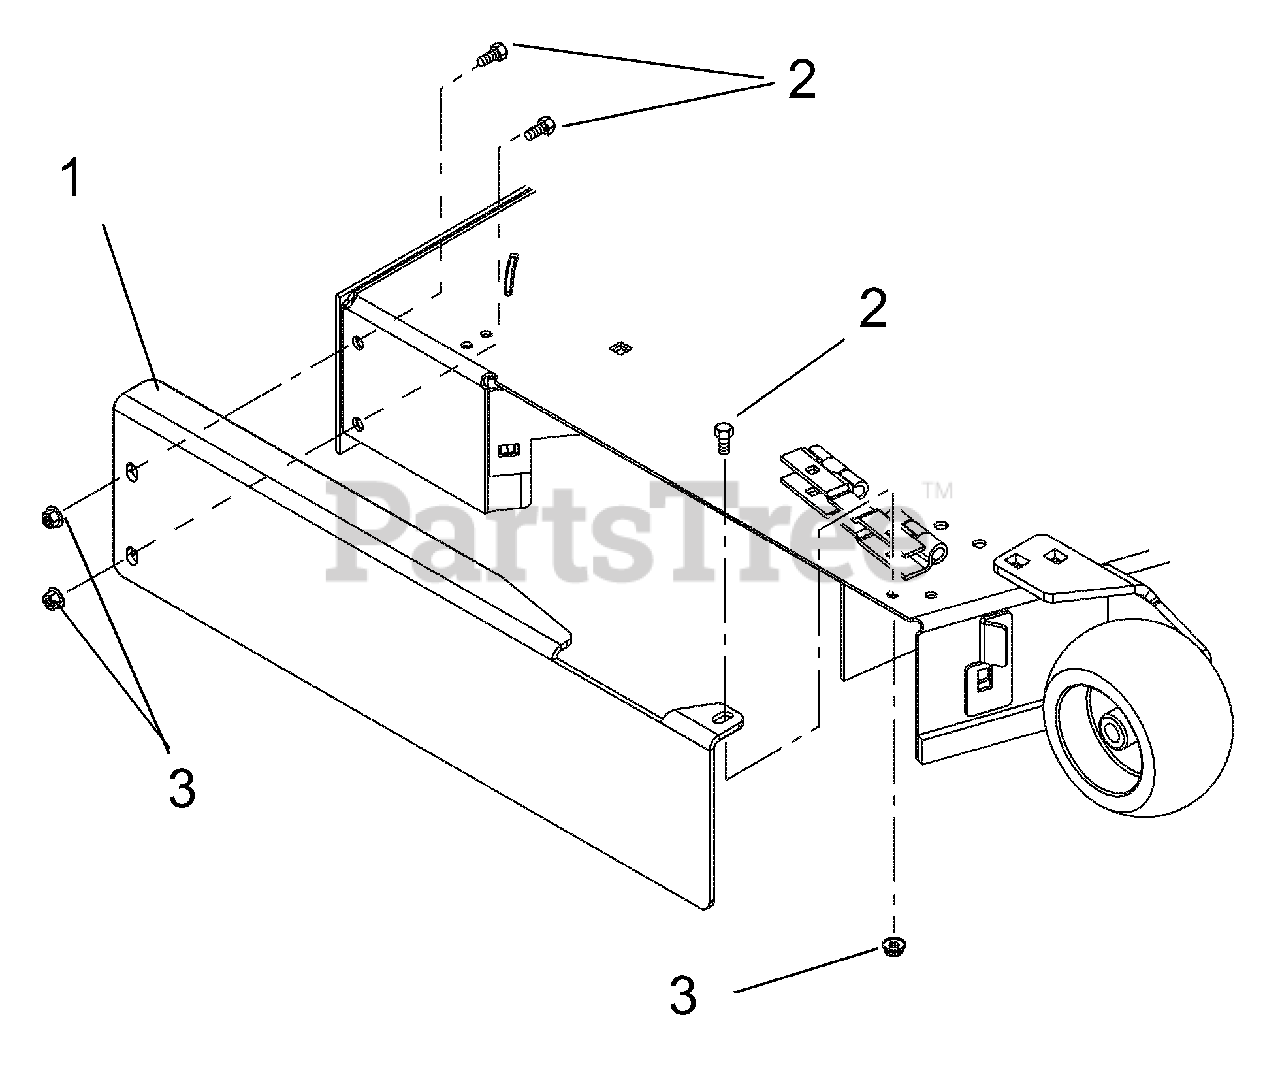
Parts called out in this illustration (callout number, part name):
1	BLOCK-OFF PLATE
2	@BLT-HEX .25-20X.75 GR5 YWZC
3	@NUT-LK-TOP-FLG .25-20 YWZC
